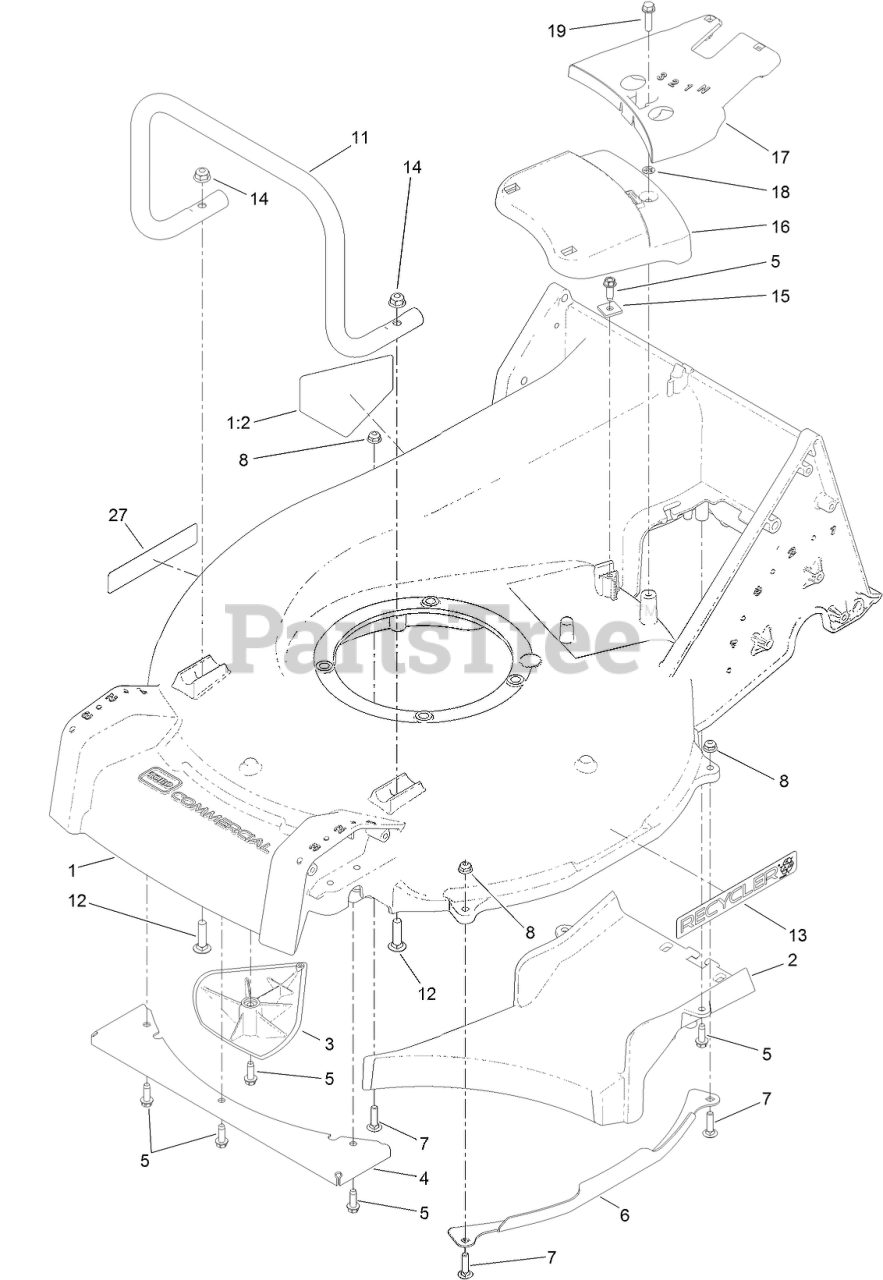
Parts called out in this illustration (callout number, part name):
1	HOUSING ASM
1:2	DECAL-DANGER
2	FLOOR-CHUTE
3	KICKER
4	GUARD-TOE, FRONT
5	SCREW-HWHTF
6	GUARD-SIDE, DECK
7	SCREW-CARR
8	NUT-HF
11	GUARD-ENGINE
12	SCREW-CARR
13	DECAL-RECYCLER
14	NUT-HF, NI
15	CLAMP-CABLE
16	COVER-BELT, FRONT
17	COVER-BELT, REAR
18	NUT-RETAINER
19	SCREW-HWHTF
